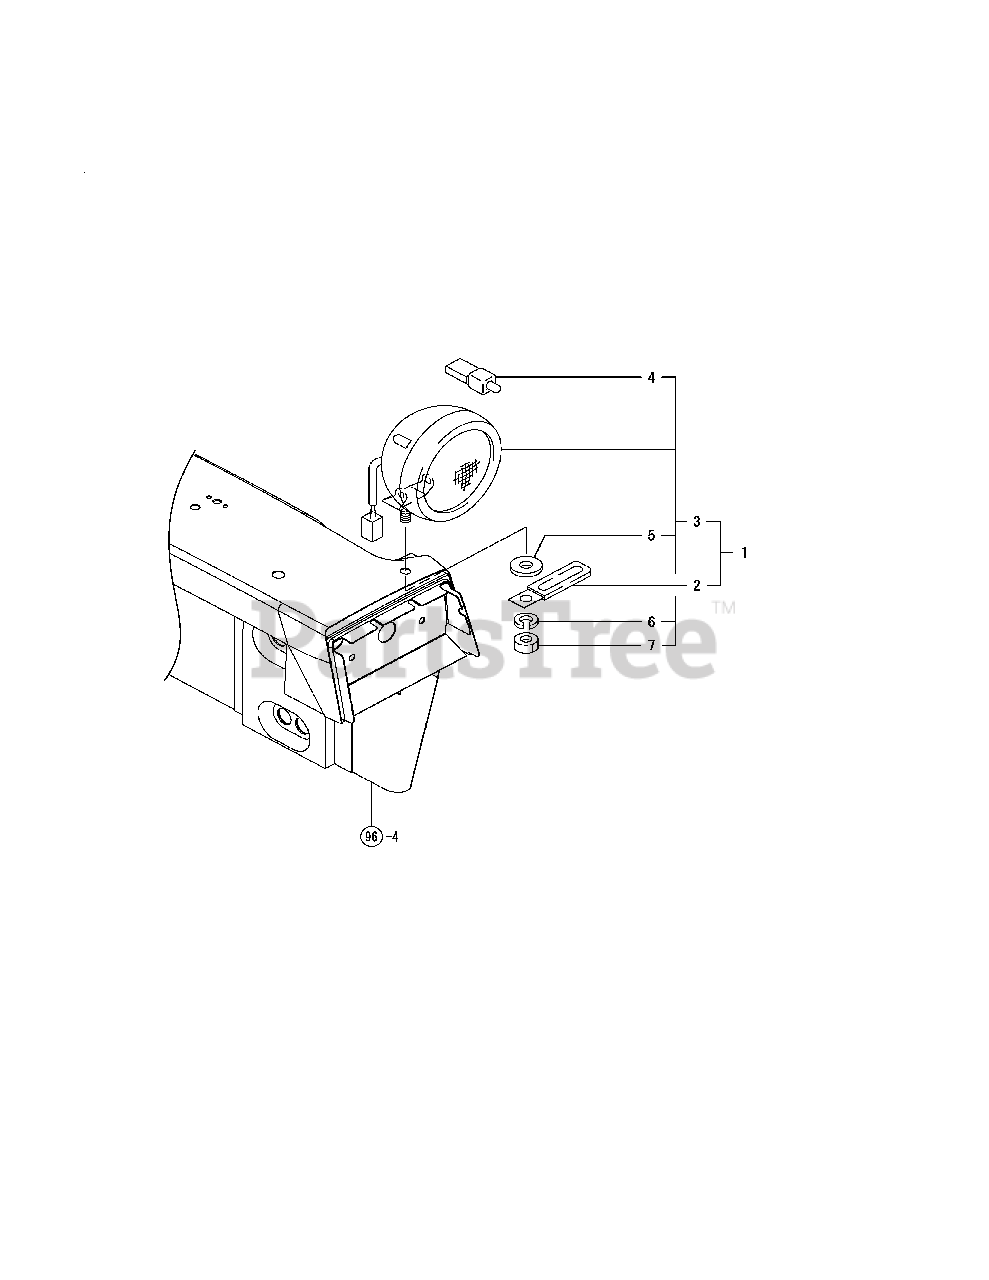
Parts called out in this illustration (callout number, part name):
2	CLAMP, WIRE HARNESS
3	WORK LAMP ASSY, SW
5	WASHER 10, POLISHED
6	SPRING WASHER 10
